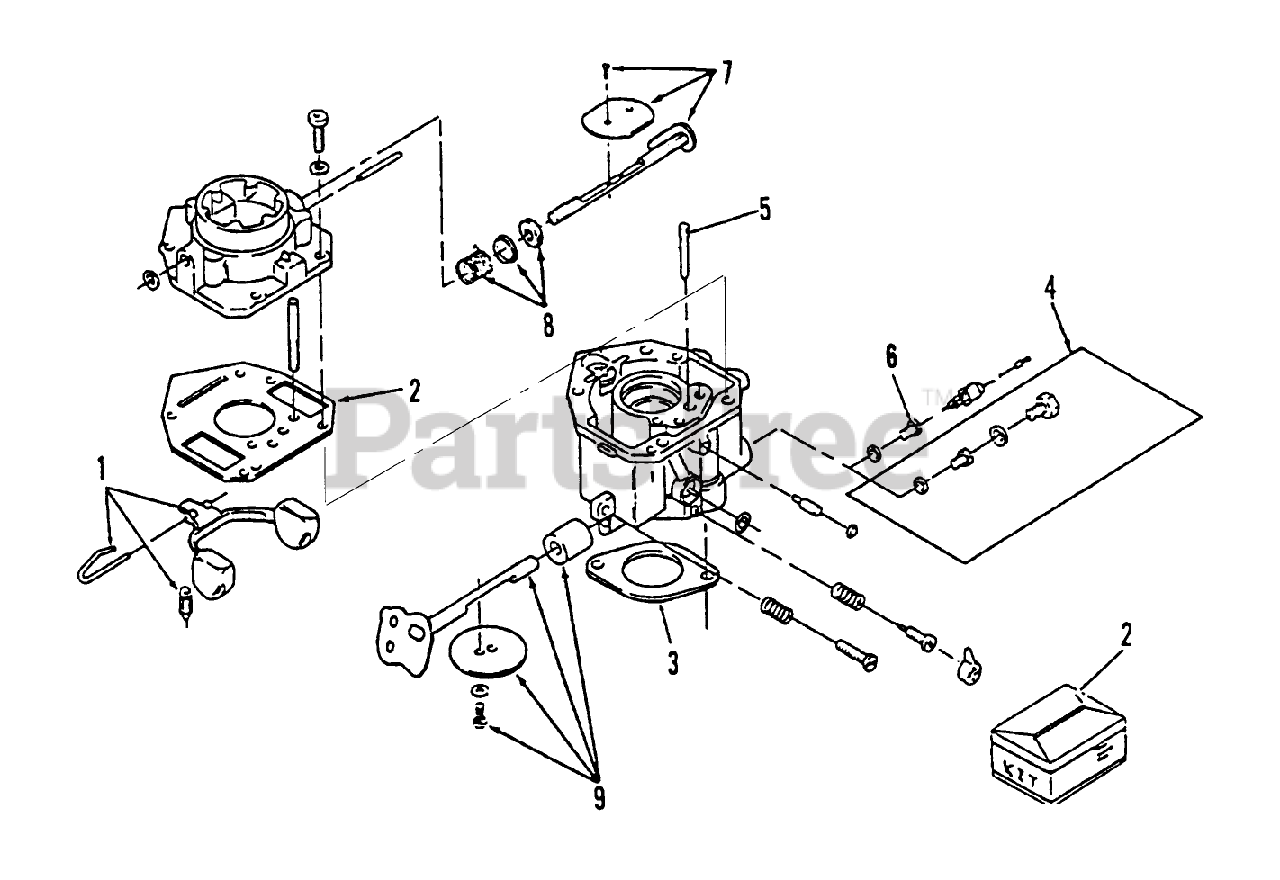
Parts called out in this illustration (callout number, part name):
1	FLOAT
2	REPAIR KIT
3	GASKET-CARBURETOR
8	CHOKE-LEVER KIT
